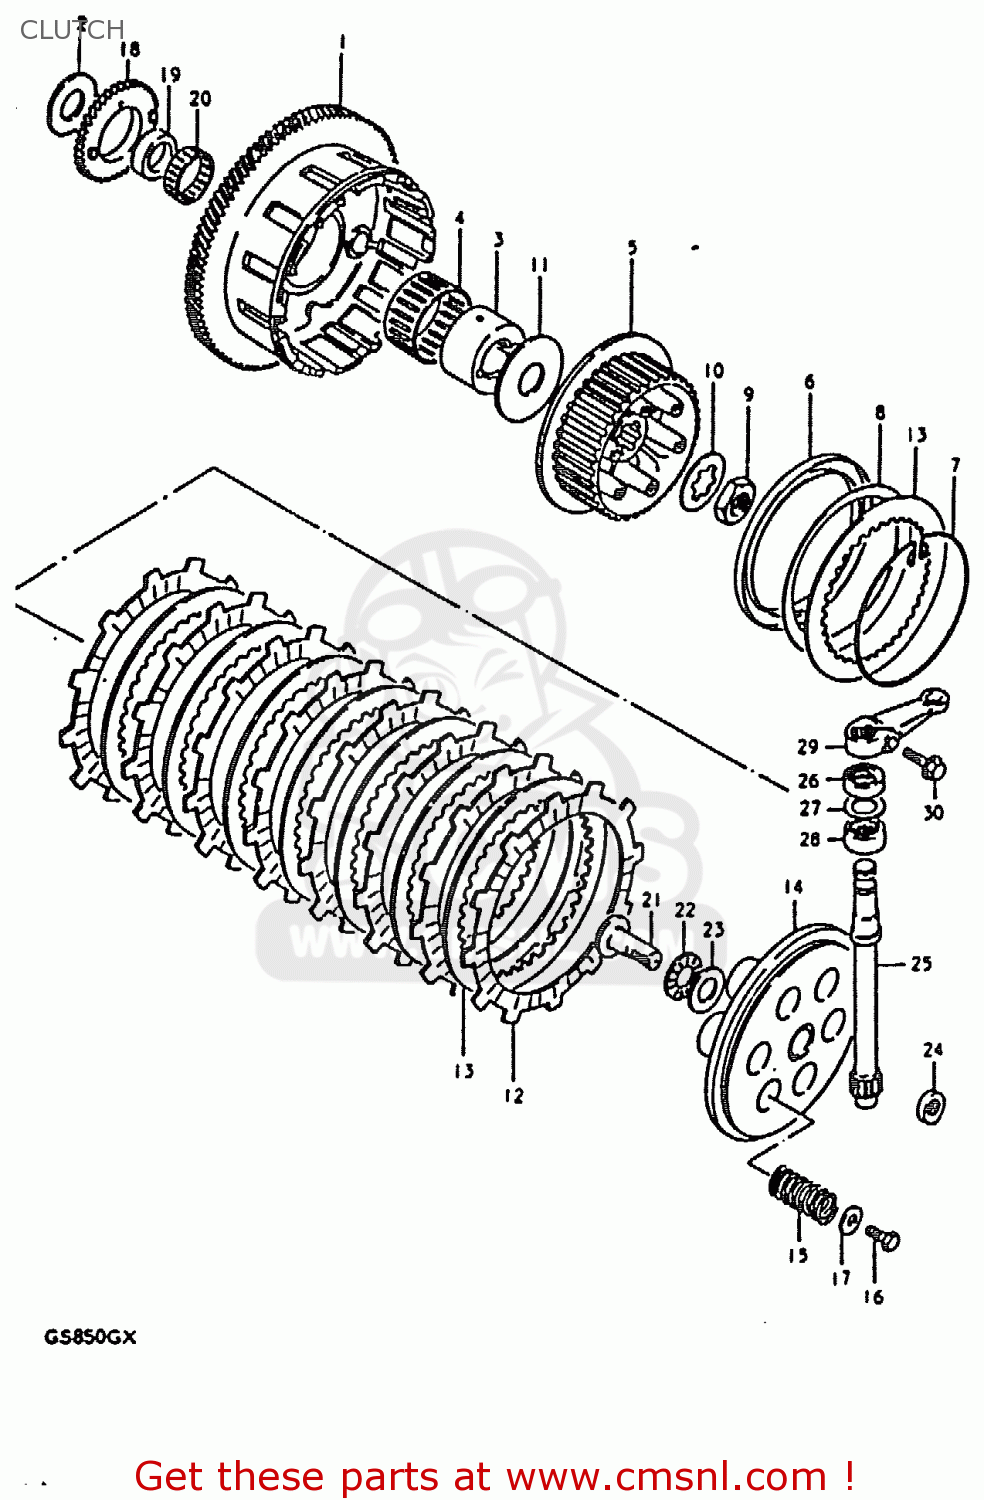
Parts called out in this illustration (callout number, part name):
1	GEAR ASSEMBLY,PRIMARY DRIVE
2	WASHER
3	SPACER,PRIMARY DRIVEN
4	BEARING
5	HUB,CLUTCH SLEEVE
6	SEAT,WAVE WASHER
7	RING,STOPPER
8	WASHER
9	NUT
10	WASHER,LOCK
11	WASHER(25X66X3.5)
12	PLATE,CLUTCH DRIVE (MCA)
13	PLATE,CLUTCH DRIVEN(T:2.0) (NAS)
14	DISC,CLUTCH PRESSURE
15	SPRING
16	BOLT, UPPER
17	WASHER
18	GEAR,OIL PUMP DRIVE
19	SPACER,OIL PUMP DRIVE GEAR
20	BEARING(36X40X10)
21	RACK,CLUTCH RELEASE
22	BEARING(15X28X2)
23	WASHER
24	SEAL,OIL(10X16X5)
25	PINION,CLUTCH RELEASE
26	OIL SEAL
27	WASHER (14.2X22X1)
28	BEARING(15X22X12)
29	ARM,CLUTCH RELEASE
30	BOLT,REAR
